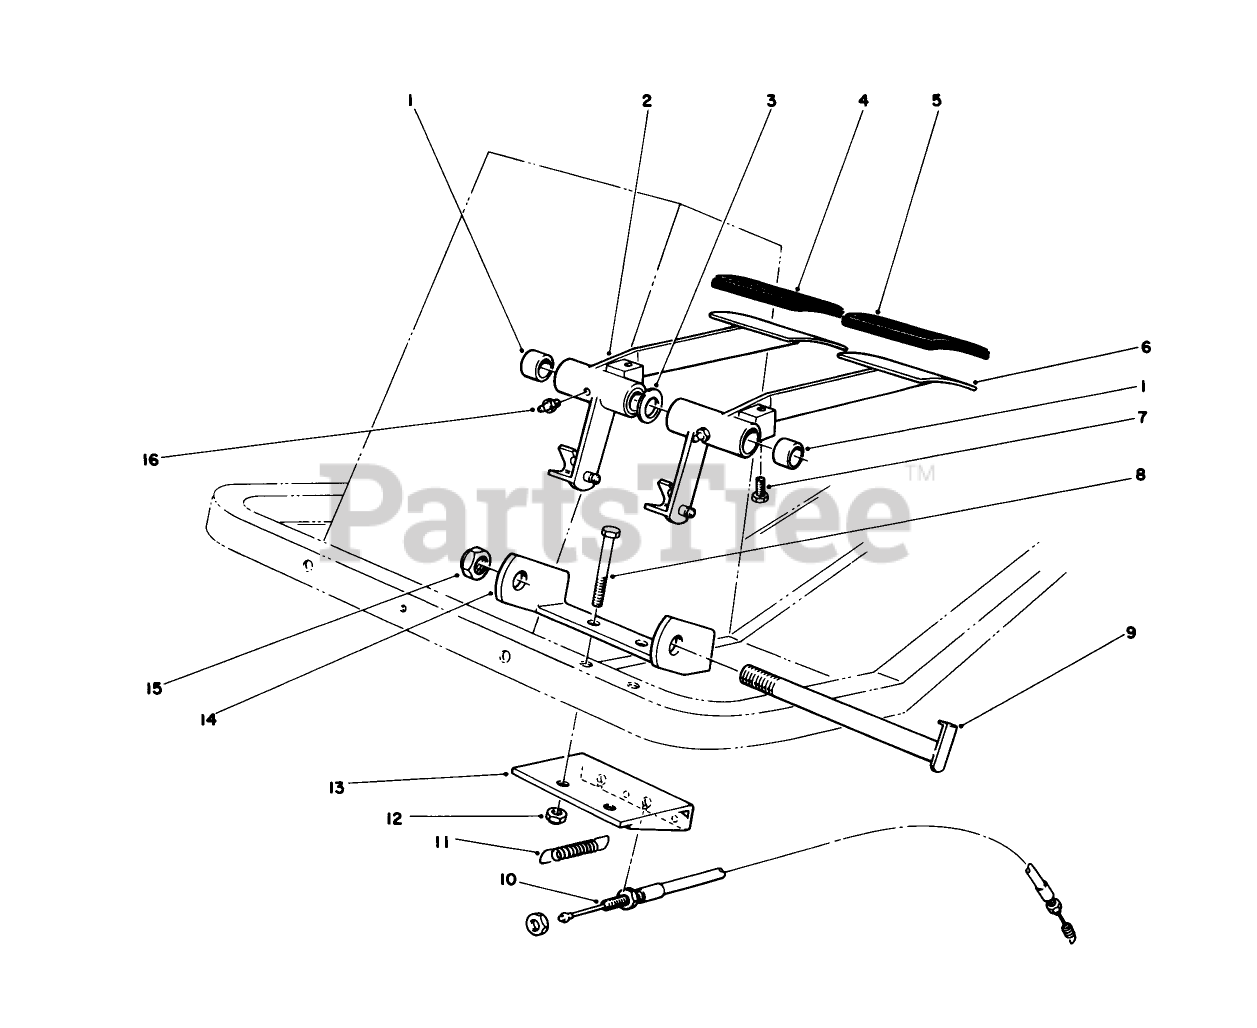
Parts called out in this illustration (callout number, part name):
1	BUSHING
2	Brake Pedal Assembly-R.H. (Incl. Ref. #1 & 16)
3	WASHER-FLAT
4	PAD-TURN, RIGHT
5	PAD-TURN, LEFT
6	Brake Pedal Assembly-L.H. (Incl. Ref. #1 & 16)
7	BOLT 60183
8	SCREW-HH
9	BRAKE PIN WA RO
10	BRAKE CABLE ASM
11	EXTENSION SPRING O
12	NUT-LOCK, NI
13	CABLE BRKT WA R
14	BRAKE PEDAL BRKT B
15	NUT-LOCK, NI
16	FITTING-GREASE
